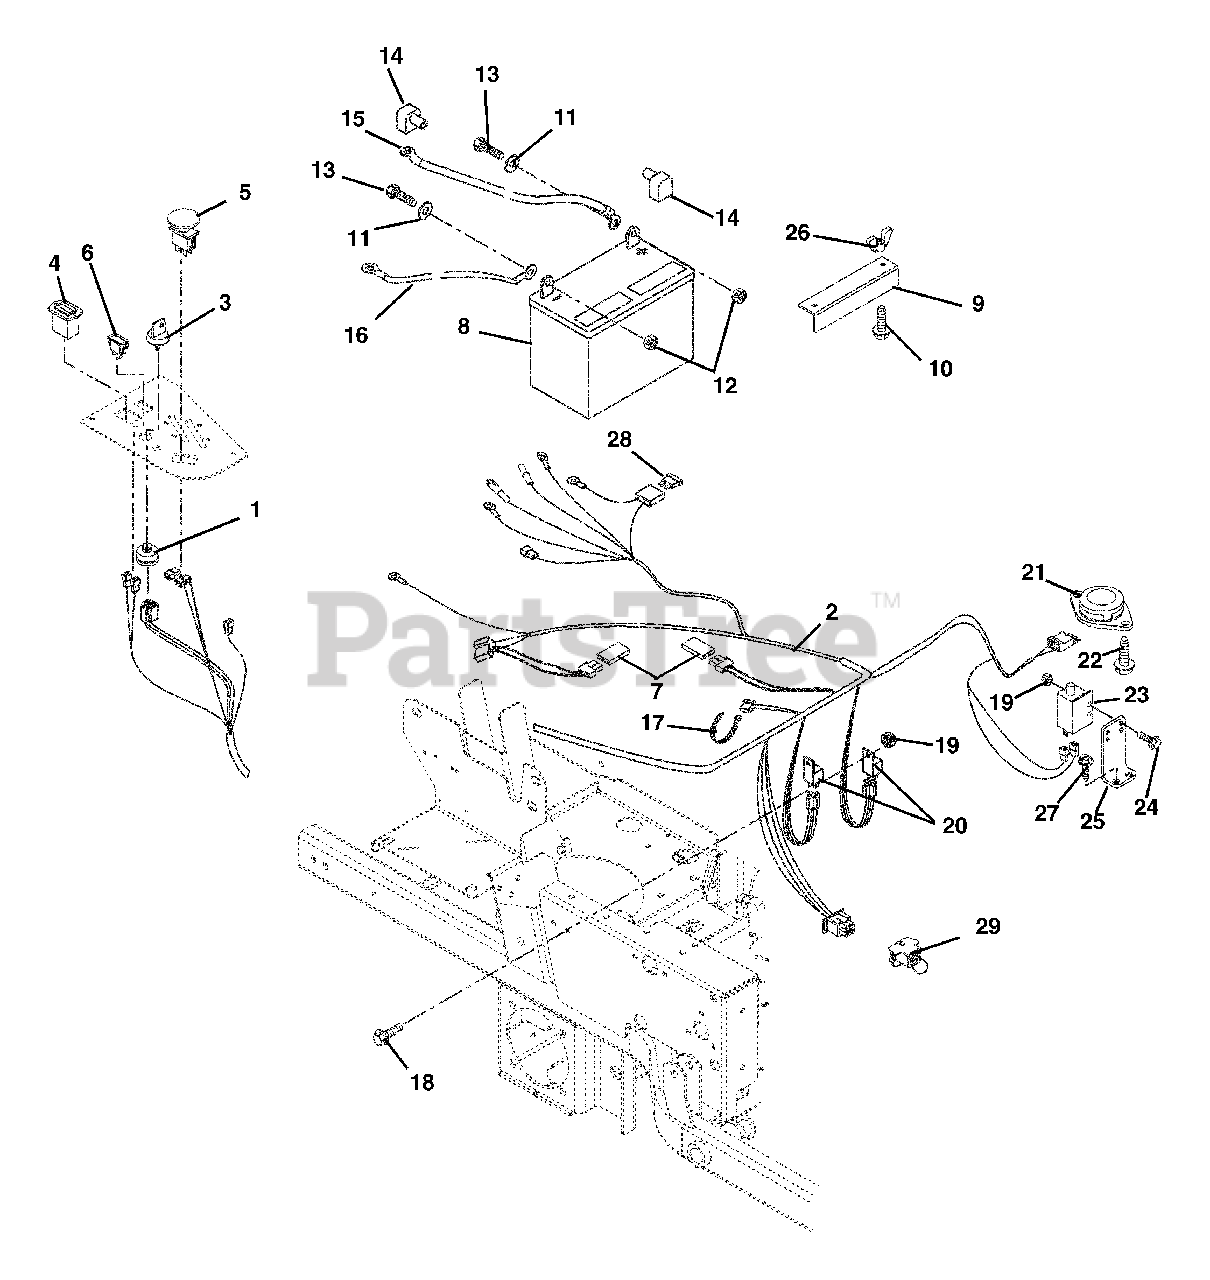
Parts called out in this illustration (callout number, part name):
1	SWITCH, IGNITION
2	HARNESS, Z-6 PIN (EYE-Q)
3	KEY, W/ SHIELD
4	HOURMETER-QUARTZ 80VDCMAX
5	SWITCH, CLUTCH
6	LIGHT,INDICATOR
7	DIODE, CONNECTOR SHELL
8	BATTERY, 300 CCA 10U1L
9	HOLD DOWN
10	BLT-RDHDSQNK .25-20X7.50 GR2YZ
11	@WSHR-FL-STL.281X.62X.065 YWZC
12	@NUT-LK-TOP-FLG .25-20 YWZC
13	@BLT-HEX .25-20X.75 GR5 YWZC
14	INSULATOR
15	CABLE, POSITIVE BATTERY 26.00
16	CABLE, NEGATIVE BATTERY 24.00
17	CABLE TIE LG 5-1/2
18	@SCR-MCH 10-24X.50 HWH YWZC
19	@NUT-LK-NYL 10-24 W/INSRT YWZC
20	RELAY
21	SEAT SWITCH
22	@SCR-TAP 12-24X.50 HWH TR YWZC
23	SWITCH- SINGLE POLE N.O.
24	@SCR-MCH 10-24X.75 HWH YWZC
25	BRAKE SWITCH MOUNT - BLACK
26	NUT-LK WING .250-20 YWZC
27	@SCR-TAP .25-20X.50 HWH TR YWZ
28	FUSE, 30 AMP.
29	HARNESS, JUMPER (EYE-Q)
